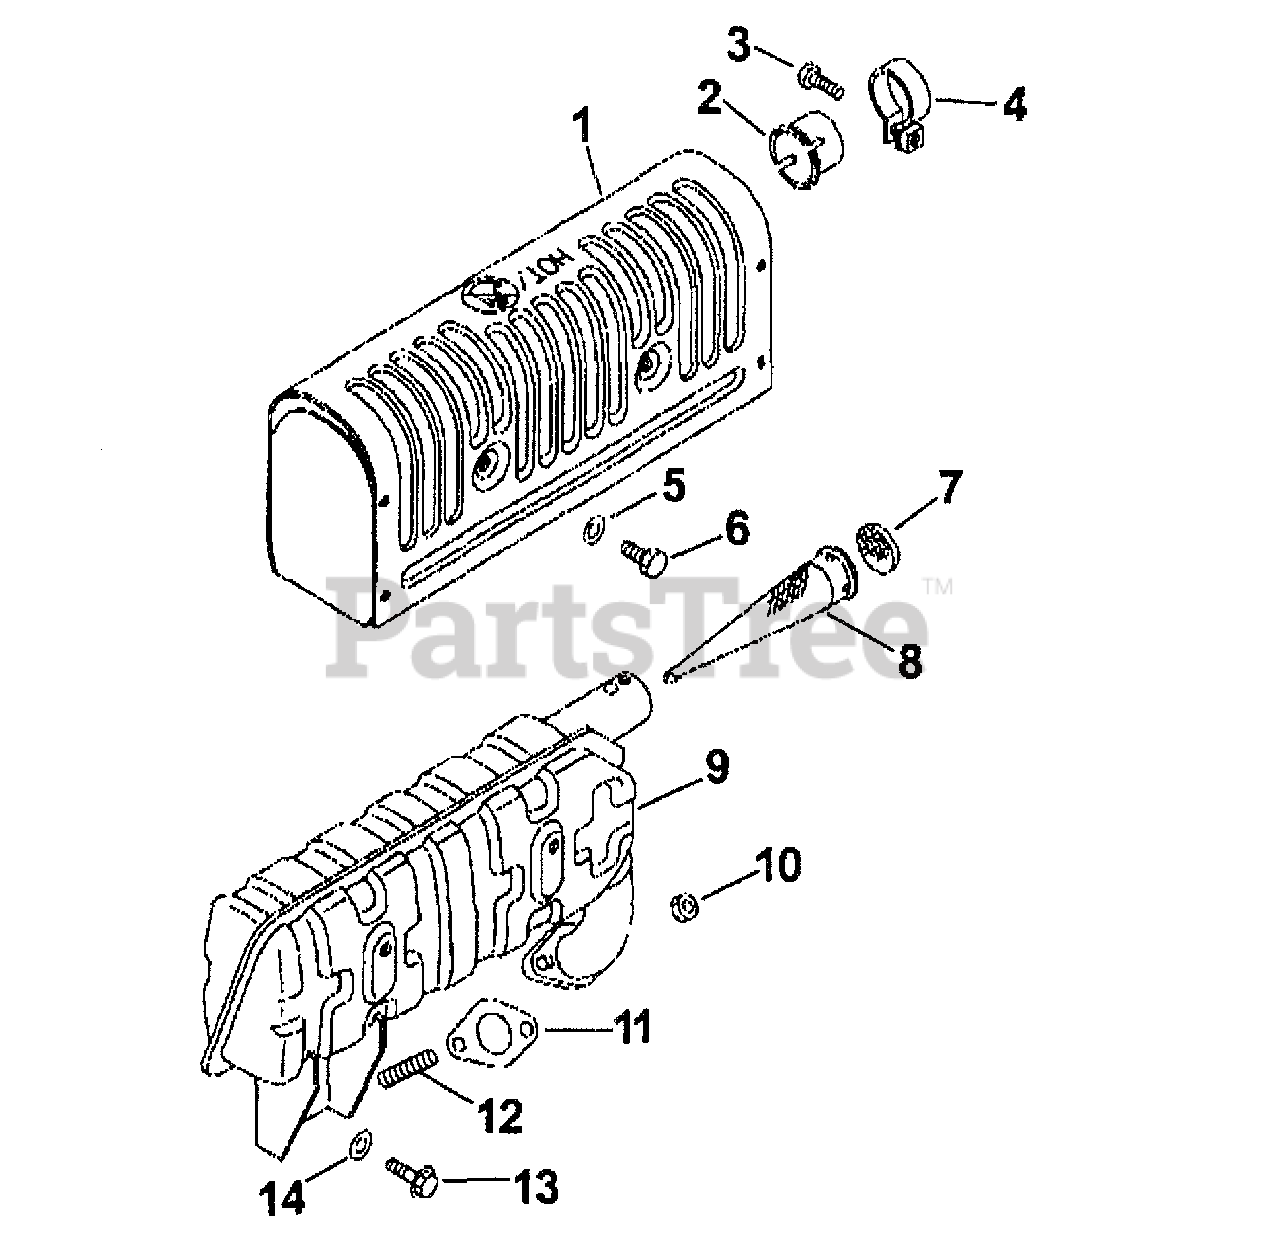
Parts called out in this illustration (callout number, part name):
1	Guard, Muffler
4	Band, Exhaust
6	Screw, Hex Flange
8	Arrestor, Spark
11	Gasket, Exhaust
12	Stud, Exhaust
